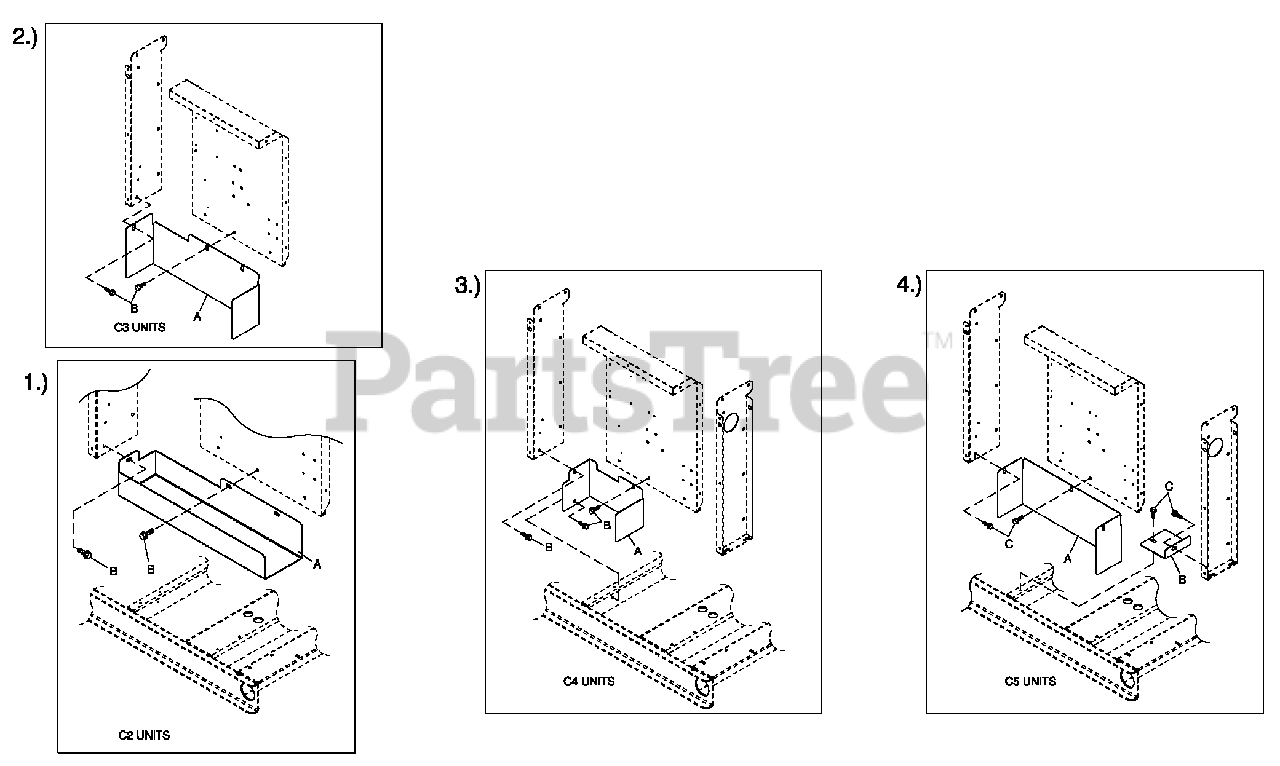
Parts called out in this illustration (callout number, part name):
1	C2 UNITS
2	C3 UNITS
3	C4 UNITS
4	C5 UNITS
A	SHIELD CONN BOX C2
B	SCREW THF M6-1 X 16 N WA Z/JS
A	SHIELD CONTROL STAND C3
B	SCREW THF M6-1 X 16N WA Z/JS
A	SHIELD CONTROL STAND C4
A	SHIELD CONTROL STAND C5
B	SHIELD CONTROL STAND C5
C	SCREW THF M6-1 X 16 N WA Z/JS
